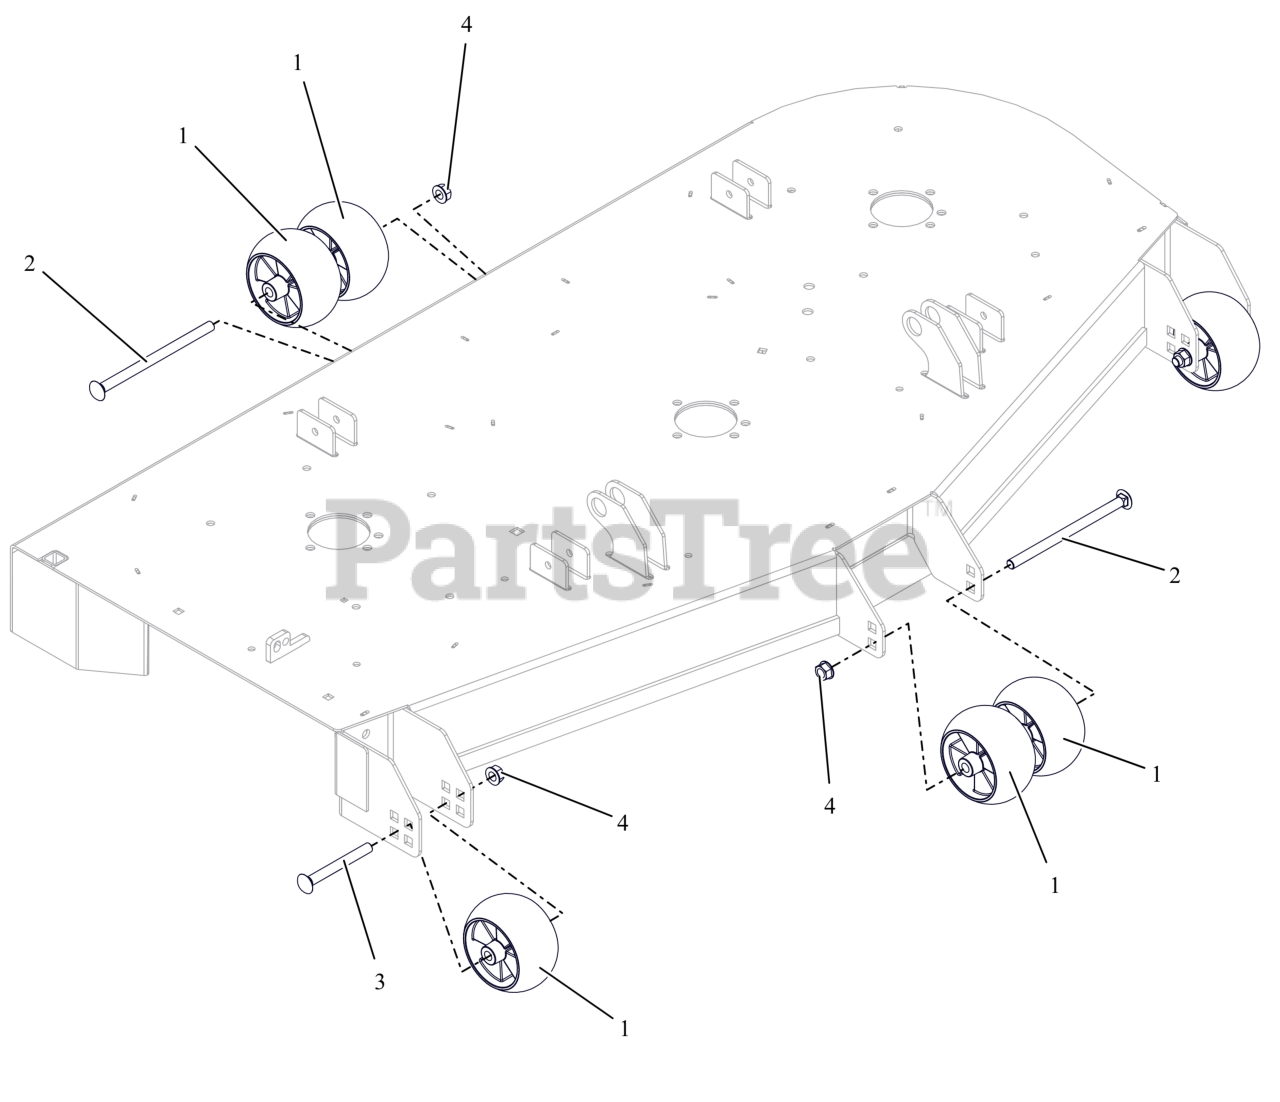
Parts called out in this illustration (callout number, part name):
1	WHEEL, ANTI SCALP - 5X3 CTR W/RIBS
2	BLT-RHSN .50-13X8.00 G5 ZCC NS
3	BLT-RHNS .50-13X4.50 G5 ZCC NS
4	NUT-LK-CTR-FLG .500-13 GG ZCC
